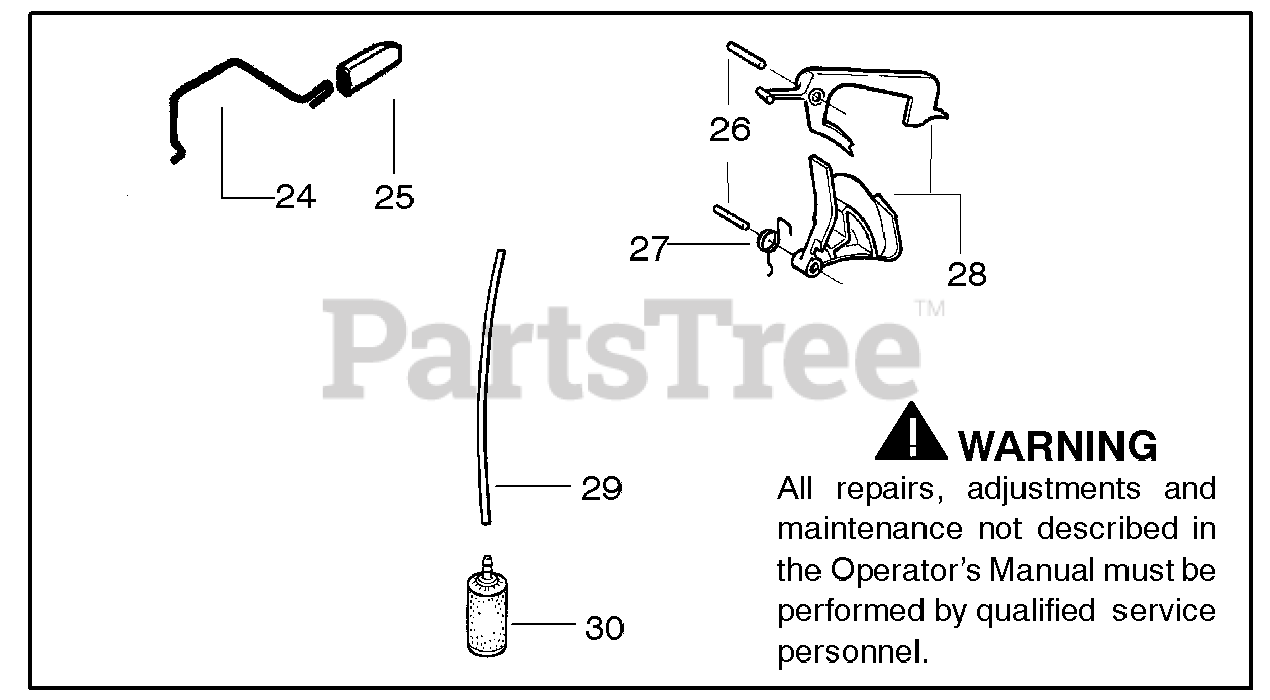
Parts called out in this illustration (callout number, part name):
24	Wire - Throttle
25	Cap - Wire
28	Kit - Throttle Trigger
29	Kit - Fuel line
30	Assy.- Fuel Pickup
